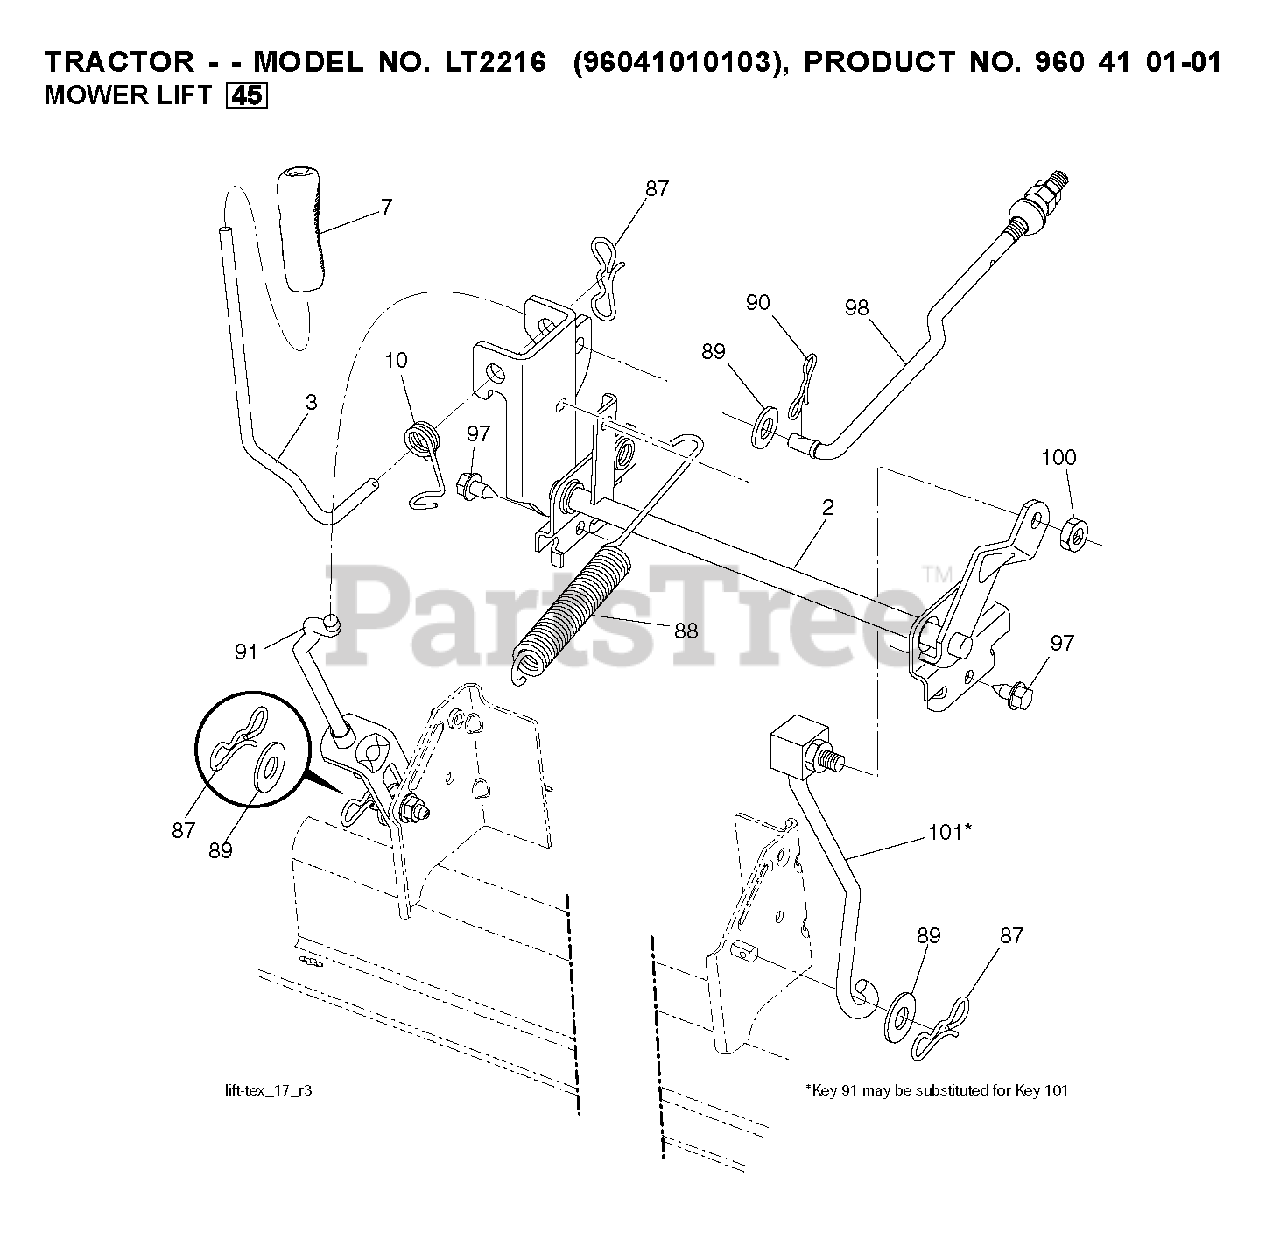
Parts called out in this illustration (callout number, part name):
2	SHAFT.ASM.CROSS.LIFT
3	LEVER.LIFT.HANDLE.LT
7	GRIP.HANDLE.LIFT.PVC.BLACK
10	SPRING.TORSION.LIFT.HANDLE
87	PIN.COTTER.7/16.BOW TI
88	SPRING.LIFT.ASSIST
89	WASHER.CLEAR.ZINC
90	PIN.COTTER.5/16.BOW TI
91	LINK.ASM.LIFT.REAR
97	SCREW, 3/8-16X3/4
98	LINK.ASM.SUSP.FRONT.MW
100	LOCKNUT
101	LINK.ASM.LIFT.FIXE.38/42/46"
